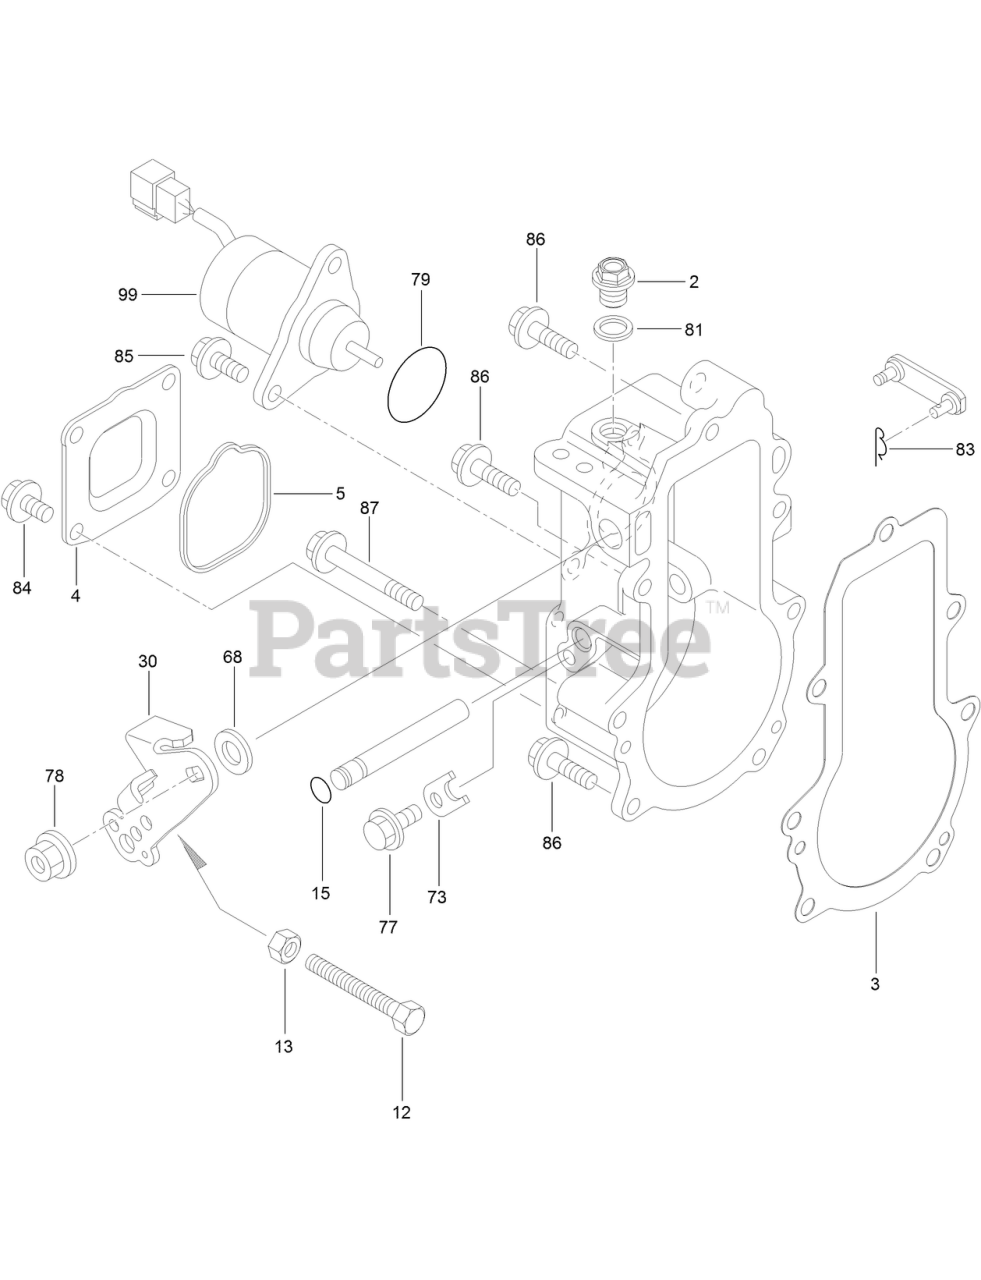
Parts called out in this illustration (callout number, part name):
3	GASKET
4	COVER-CASE, GOVERNOR
5	GASKET
12	BOLT-LIMIT, IDLE
15	O-RING
30	LEVER-CONTROL
68	SHIM SET
73	STOPPER-SHAFT
78	NUT-M8
79	O-RING
81	WASHER-SEAL
99	STOP-SOLENOID
